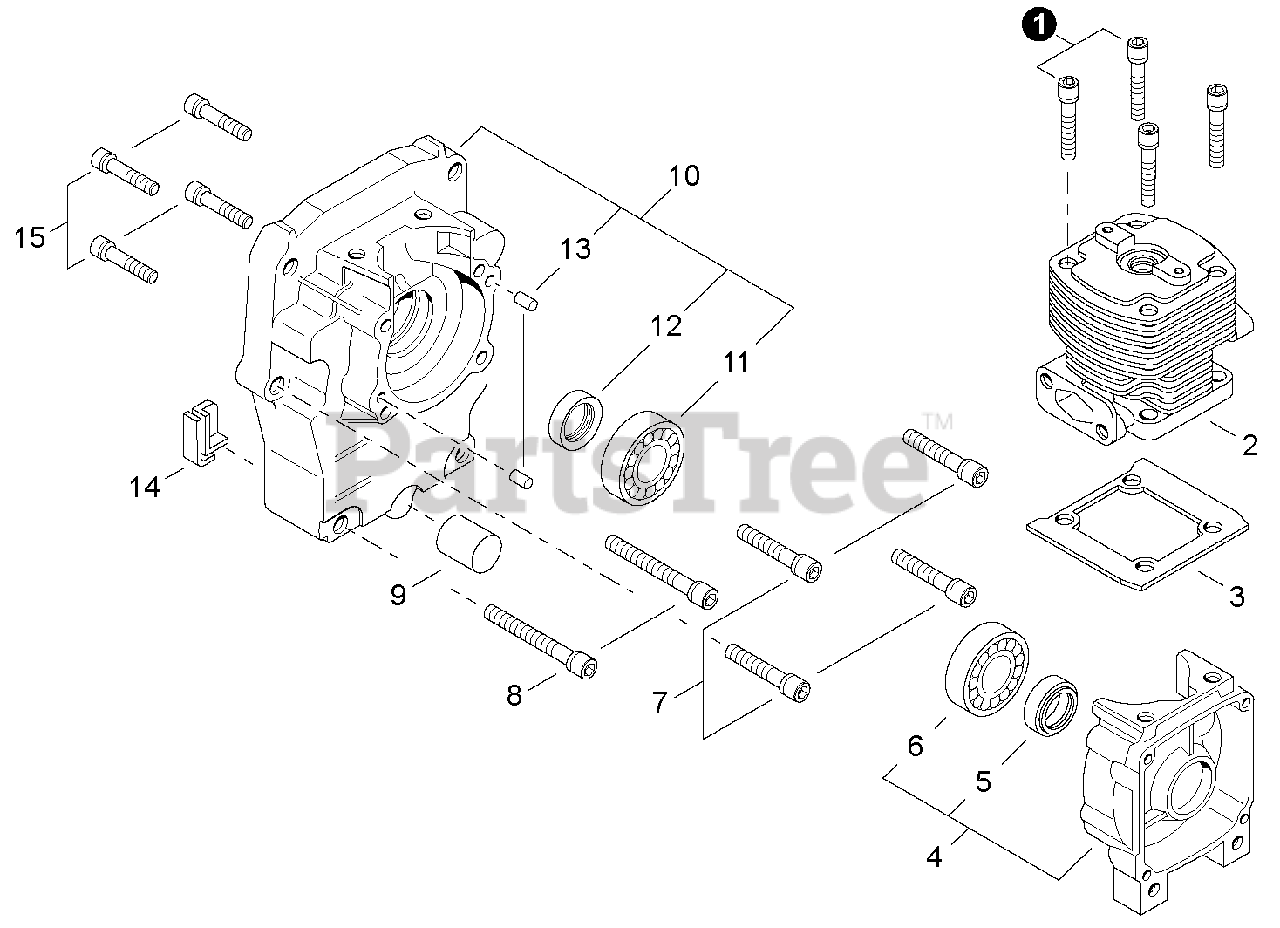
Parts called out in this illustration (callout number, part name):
1	BOLT 5
2	CYLINDER
3	GASKET, CYLINDER
4	CRANKCASE ASSY, S
5	SEAL, OIL 16
6	BEARING, BALL 6202 C3
7	BOLT, ADHESIVE M6×30
8	BOLT, ADHESIVE M6×45
9	CUSHION
10	CRANKCASE ASSY, M
11	BEARING, BALL 6202 C3
12	SEAL, OIL 16
13	PIN, LOCATING 5×10
14	GROMMET
15	BOLT, ADHESIVE M5×30
